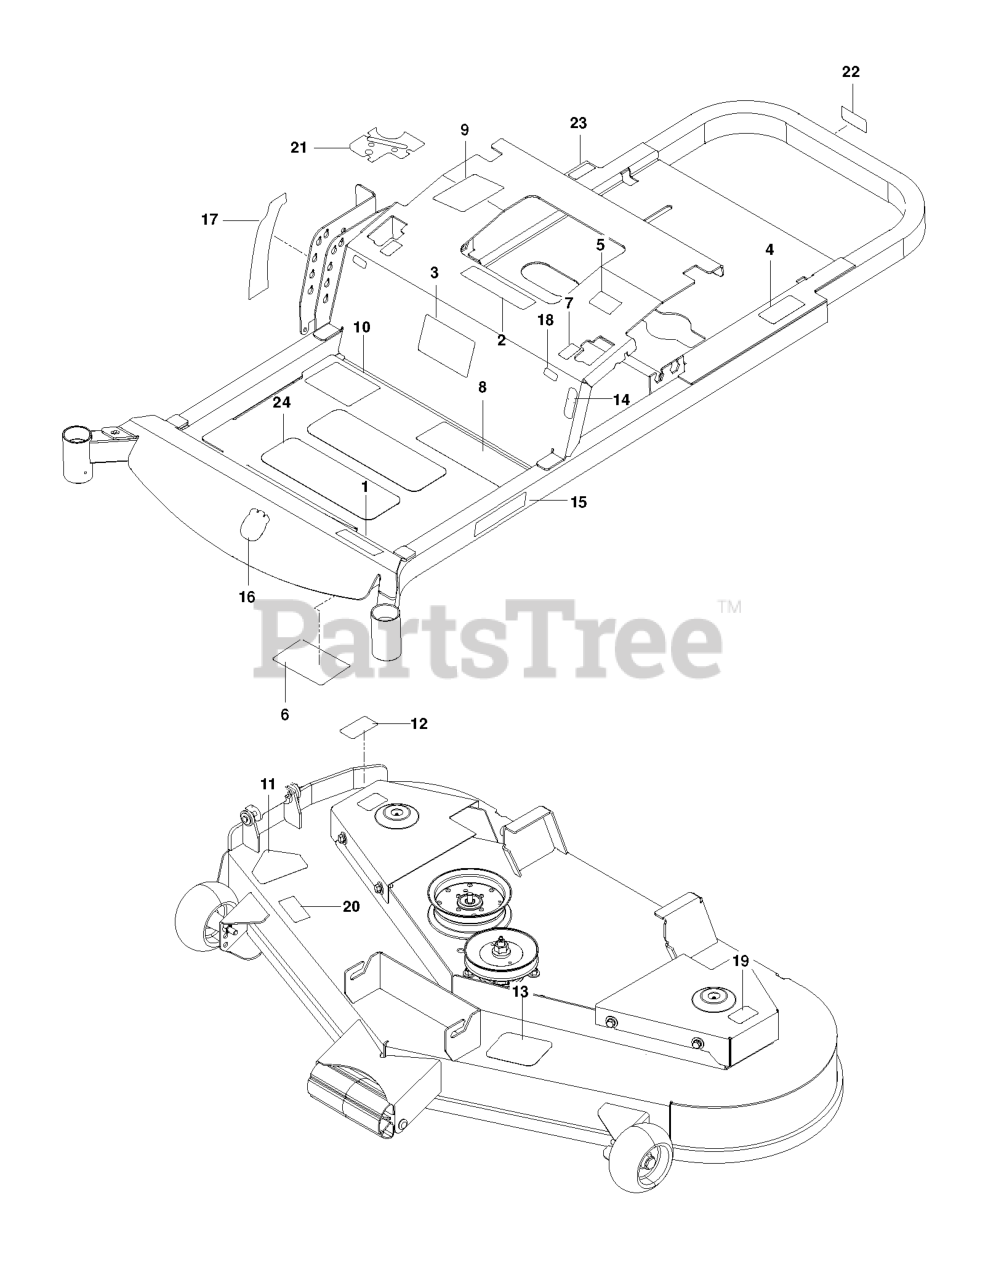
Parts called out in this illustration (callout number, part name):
1	DECAL RZ4824F
2	EURO DECAL-BATTERY WARNIN6
3	DECAL, START
4	DECAL, DO NOT TOW
5	DECAL, EXITING MOWER
6	DECAL, SERVICE
7	DECAL, MOTION CONTROL
8	DECAL, SAFETY WARNING
9	DECAL, CUSTOMER RESPNSIBILITY
10	DECAL, WARNING
11	DECAL, CPSC
12	DECAL, CAUTION
13	DECAL, BELT ROUTING
14	DECAL, PARK BRAKE
15	RP.DECAL.BADGE.170MM.TEXTLOGO
16	DECAL.AUGER.HUSQ.CROWN.SNOW
17	DECAL, DECK HEIGHT, HUSQ
18	DECAL, F.S.T.
19	DECAL, NO STEP
20	DECAL, EURO SEVERING
21	DECAL, CTRL PANEL, HUSQ
22	DECAL, PROP. 65
23	DECAL, WARNING SPARK ARRESTOR
24	ANTI-SKID PAD
